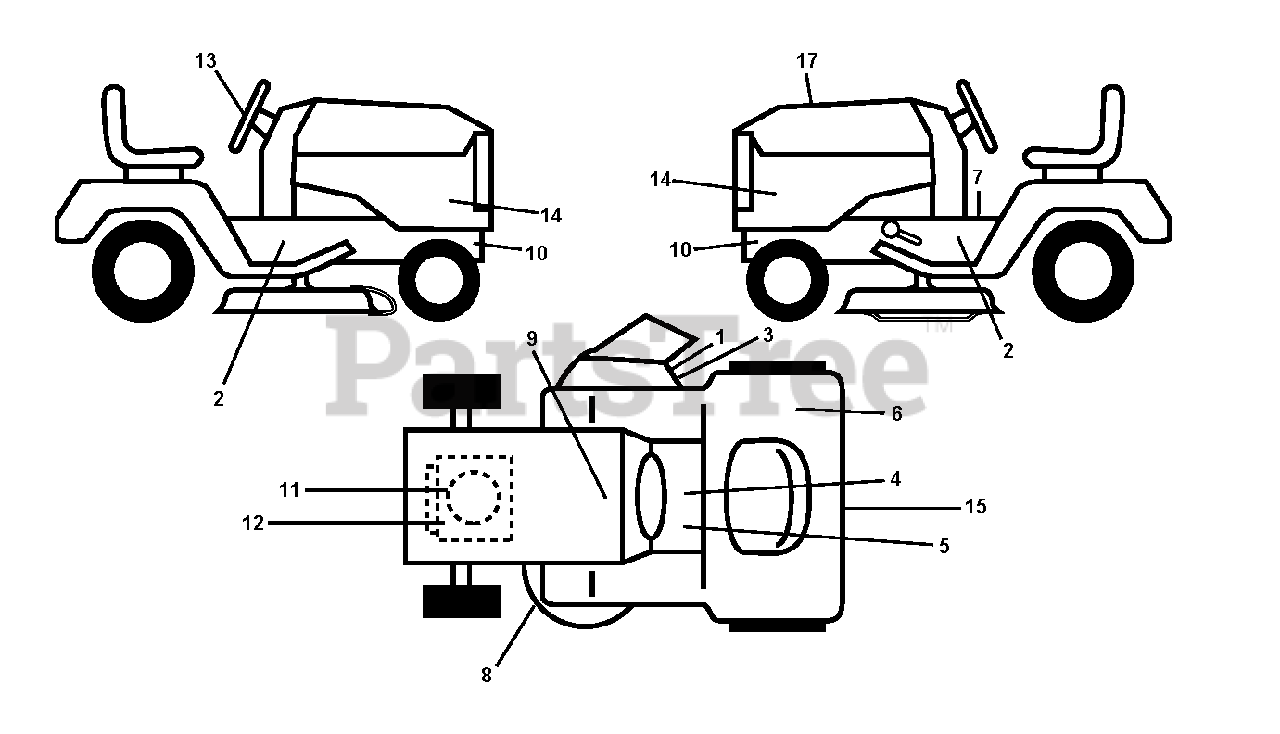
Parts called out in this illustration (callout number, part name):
1	DECAL.INTERNATIONL.CUTFINGER
3	DECAL, DEFLECT WARNING
4	DECAL PARK BRAKE
8	DECAL V BELT SCHEMATIC
9	DECAL BTRY SYMBOLS
